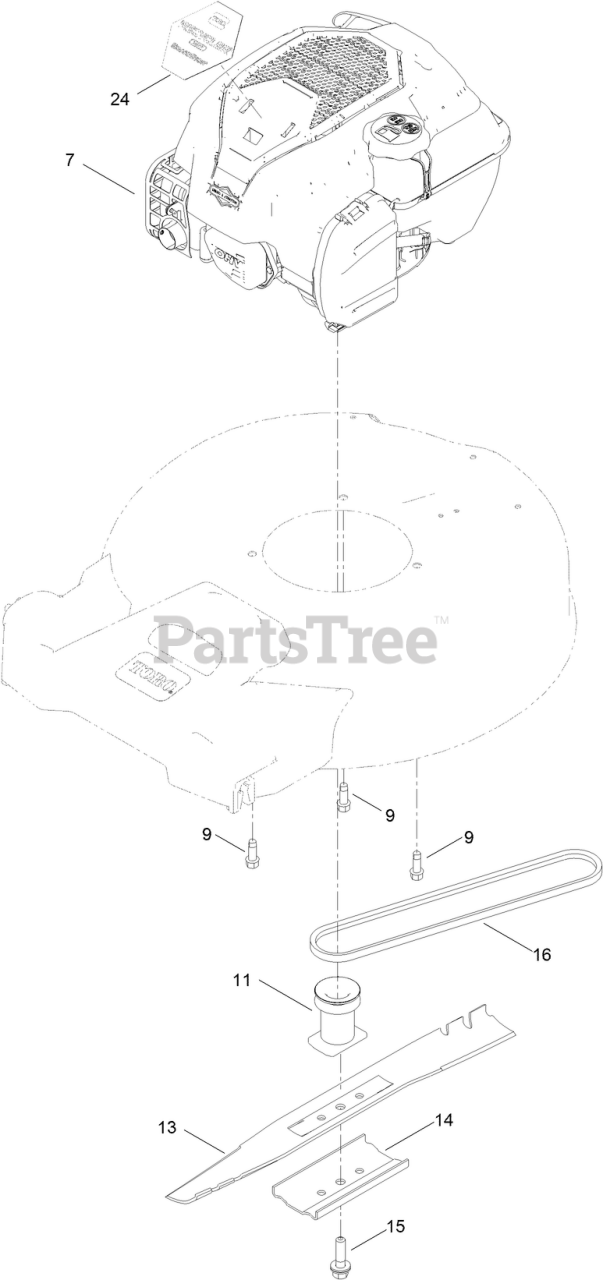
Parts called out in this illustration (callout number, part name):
9	SCREW-TAPTITE
11	DRIVER-BLADE
13	BLADE-21IN
14	SUPPORT-BLADE
15	BOLT-BLADE
16	BELT-V
24	DECAL-BRIGGS GTS SS CE
